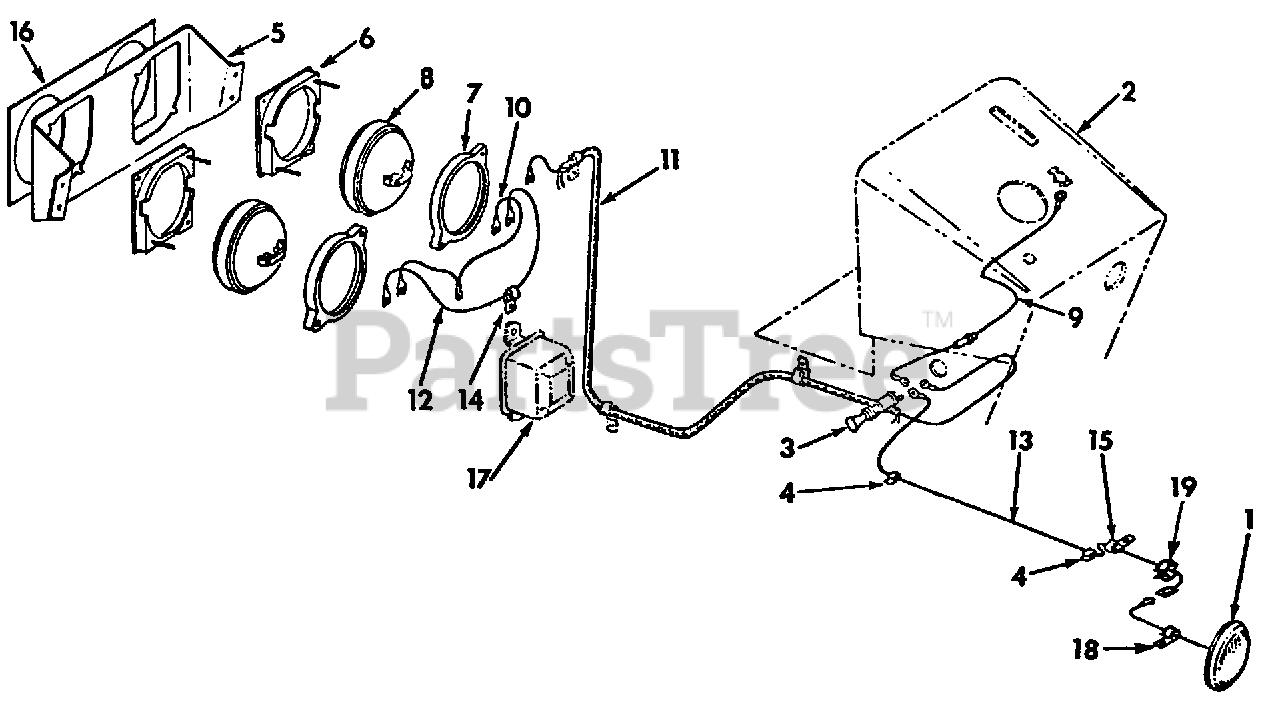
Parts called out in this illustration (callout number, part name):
1	Taillight Assy
2	Pedestal Assy
3	Switch Assy, Lighting
4	Clip, Taillight Cable
5	Panel Assy, Headlight Mounting
6	Rim, Headlight
7	Ring, Headlight Clamp
8	Unit Assy, Sealed Beam Headlight
9	Cable Assy, Lighting Switch to Charge Indicator
10	Cable Assy, Headlight to Ground
11	Harness Assy, Cable
12	Cable Assy, RH Headlight to LH Headlight
13	Cable Assy, Lighting Switch to Taillight
14	Clip, RH Headlight to LH Headlight Cable
15	Clip, Lighting Switch to Tail- light Cable
16	Product Graphic, Headlight Panel
17	Regulator Assy, Voltage
18	Clip, Taillight
19	Clip, Cable
